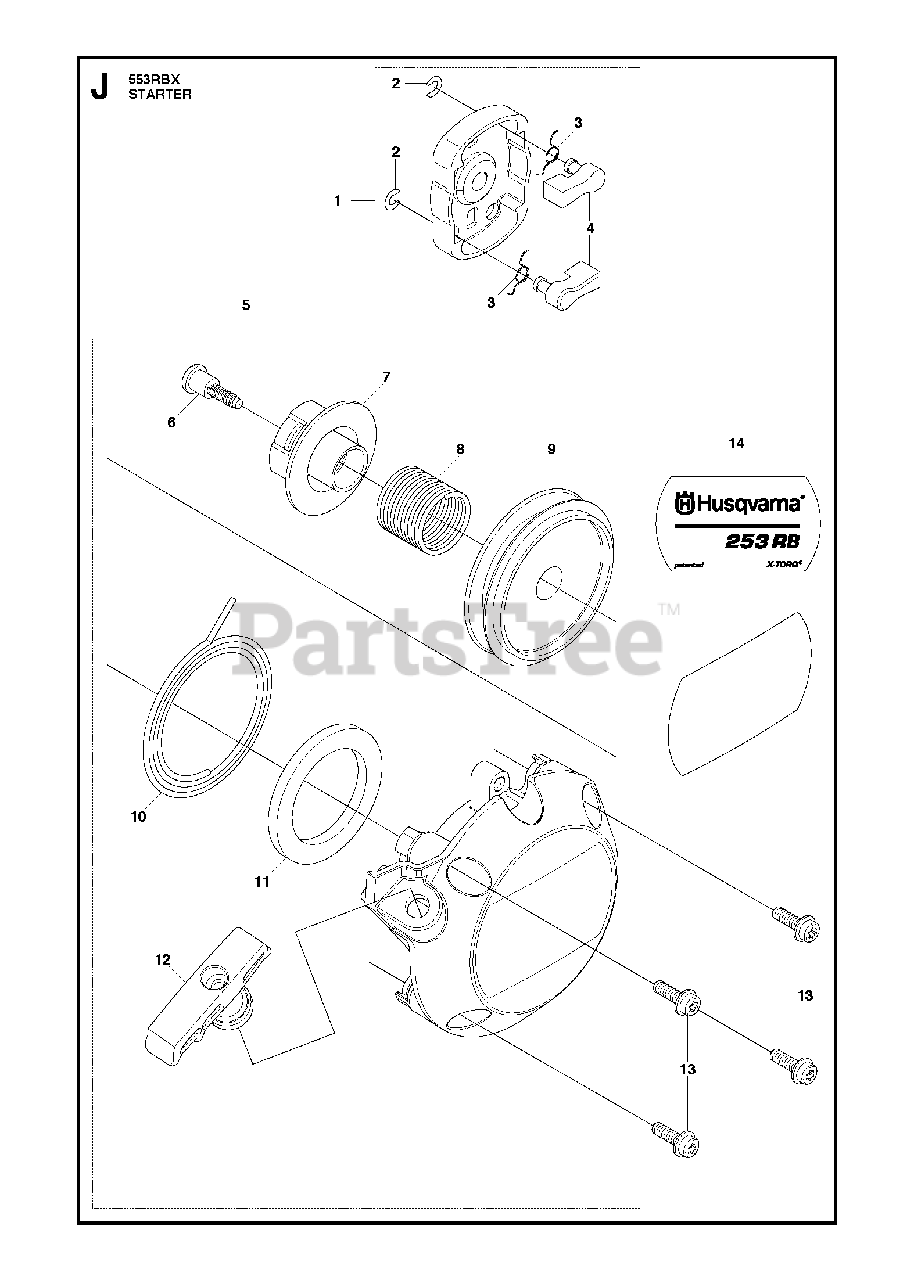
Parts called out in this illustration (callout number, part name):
2	RP_E-RING
8	SPRING
9	REEL
10	ROPE
11	SPRING, SPIRAL
12	KNOB
13	BOLT TORX
